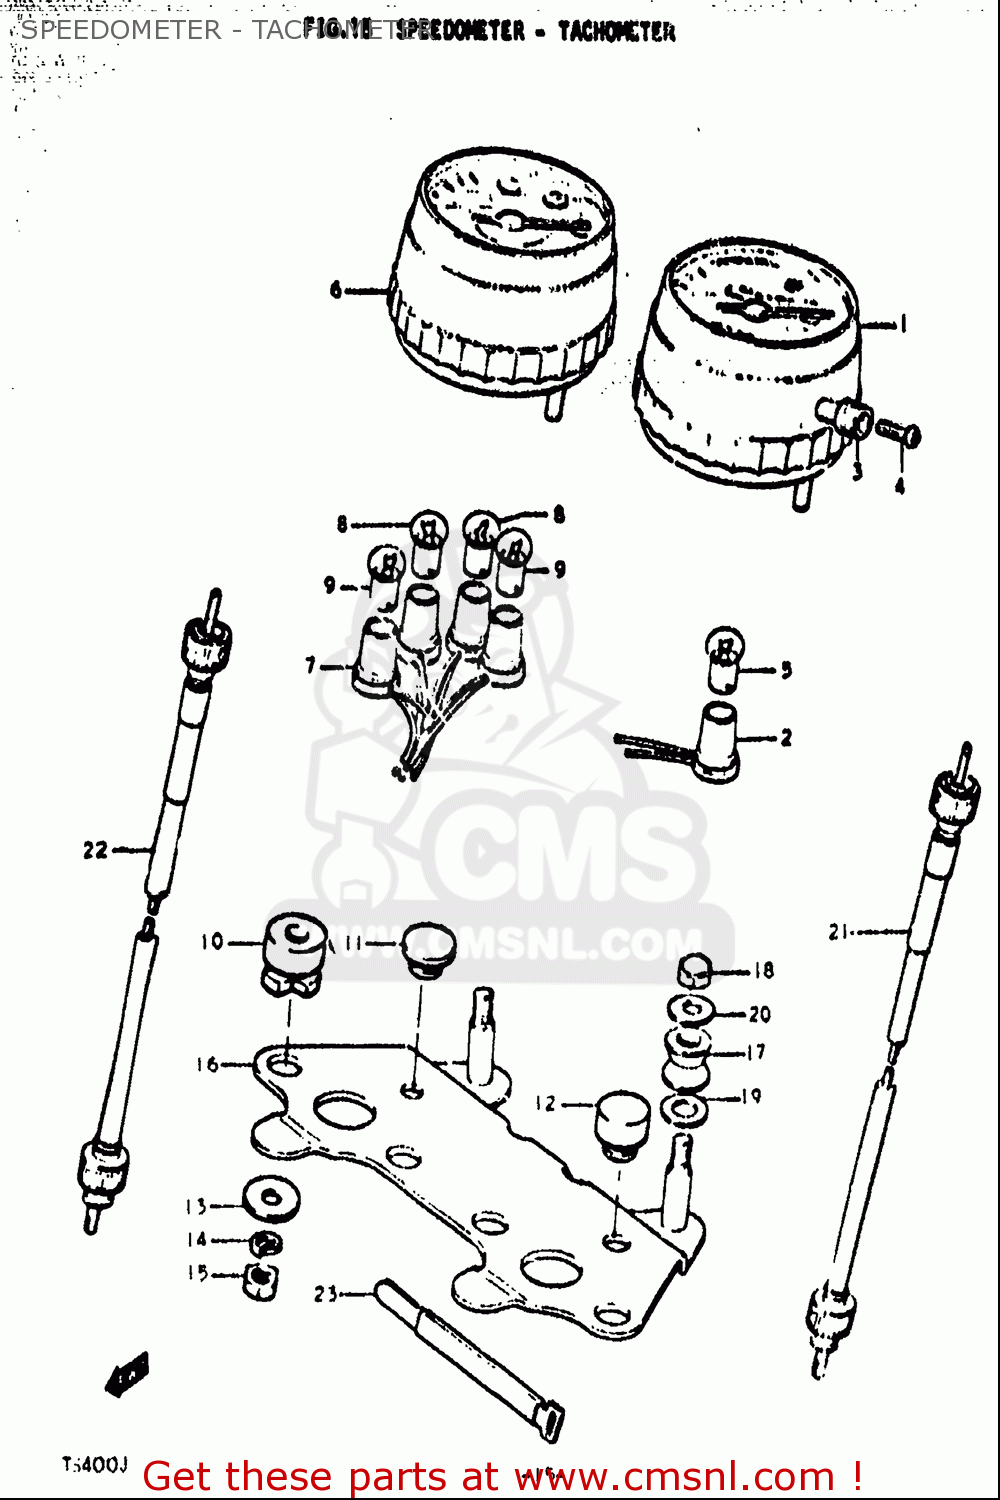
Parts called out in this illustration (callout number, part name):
3	KNOB, TRIP METER
4	SCREW(2X6)
5	BULB(12V3.4W,STANLEY,A72A)
8	BULB(12V1.7W,A71A)
9	BULB(12V3.4W,STANLEY,A72A)
10	CUSHION,METER NO.1
13	WASHER(6.5X18X1.6)
14	WASHER,LOCK
15	NUT
17	CUSHION
18	NUT
19	WASHER
20	WASHER(6.5X18X1.6)
21	CABLE ASSY,SPEEDOMETER
23	CLAMP
